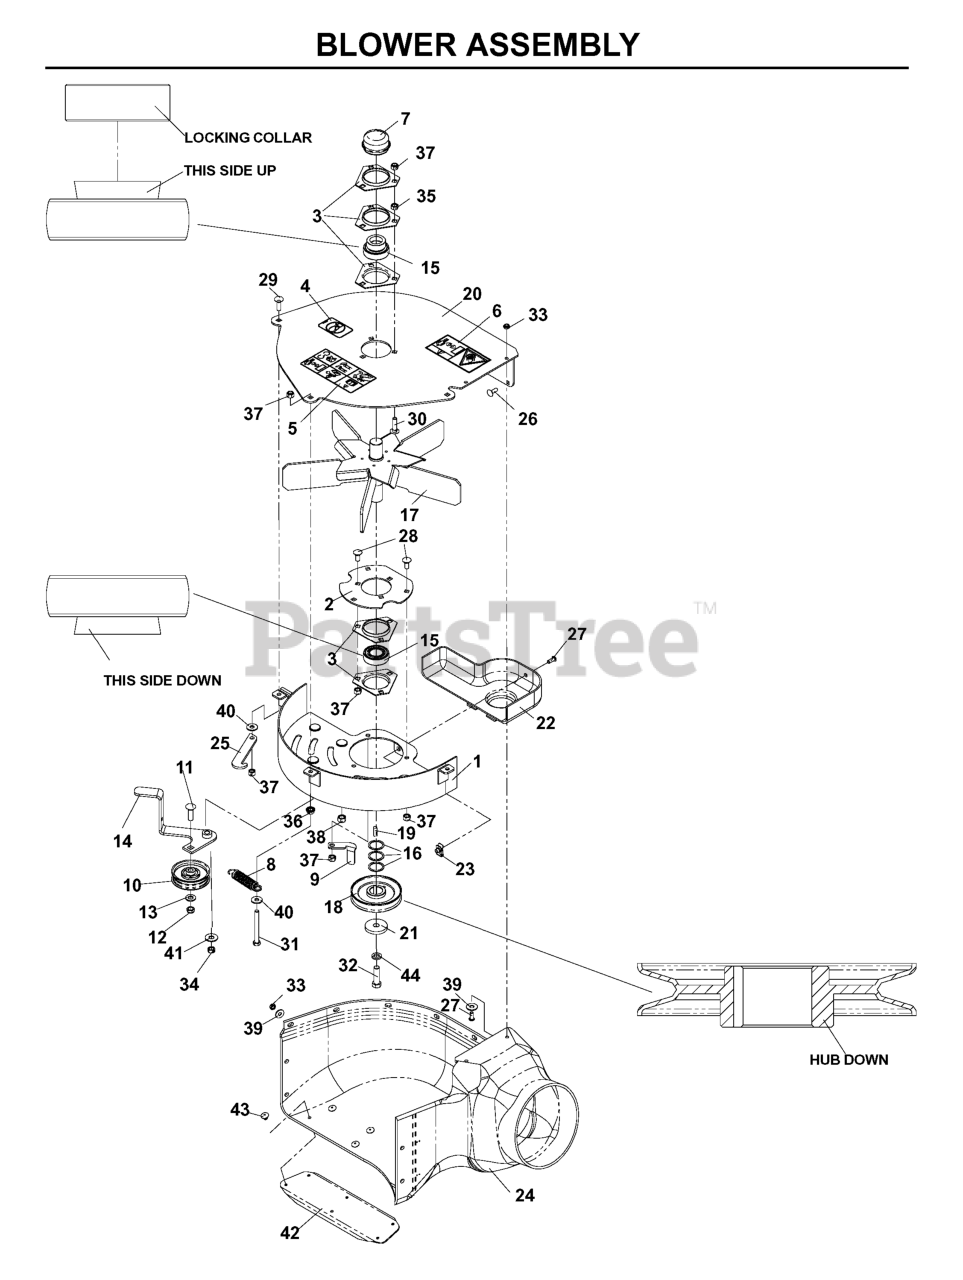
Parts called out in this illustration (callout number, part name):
1	FLOOR WELDMENT
2	BEARING PLATE
3	BRG FLANGE
4	DECAL, NO STEP
5	DECAL, EURO WARNING
6	EURO DECAL, IMPELLER
7	GREASE CAP
8	SPRING-TRANS
9	BELT GUIDE
11	RHSNB 3/8-16 X 1-1/4
12	NUT HEX 3/8-16 NYLON, THIN
13	WASHER 3/8 SAE FLAT
15	BEARING KIT-2 PCS
16	BUSHING.MACHINE.18.GAUGE
17	SPINDLE BLOWER FAN
19	KEY 1/4 SQ X 3/4
20	FAN COVER W/DECALS
21	SPINDLE WASHER
22	PULLEY SHEILD
23	1/4C - U TYPE RETAINER
24	BLOWER HOUSING
25	KEEPER, IDLER
26	RHSNB 1/4C X 3/4
27	SCR 1/4-20 X 5/8 BTN SKT HD ZD
28	BOLT 5/16C X 3/4" CARRIAGE
29	RHSNB 5/16C X 1
30	BOLT, CARRIAGE 5/16X1-1/4
31	HCS 5/16C X 2-3/4
32	HCS 7/16F X 1 1/2
33	JAM NUT 1/4C (2 2 PW01)
34	NUT 3/8C CENTERBLOCK
35	NUT 5/16C HEX
36	NUT 5/16C WHIZ
37	NUT 5/16 NYLOC
38	NUT 3/8-16 NYLOC
39	WASHER 1/4 FLAT
40	WASHER 5/16 FLAT
41	WASHER 3/8 FLAT
42	BLOWER SUPPORT
43	RIVET E/16 X 1/4 LG FLG
44	WASHER 7/16 LOCK
